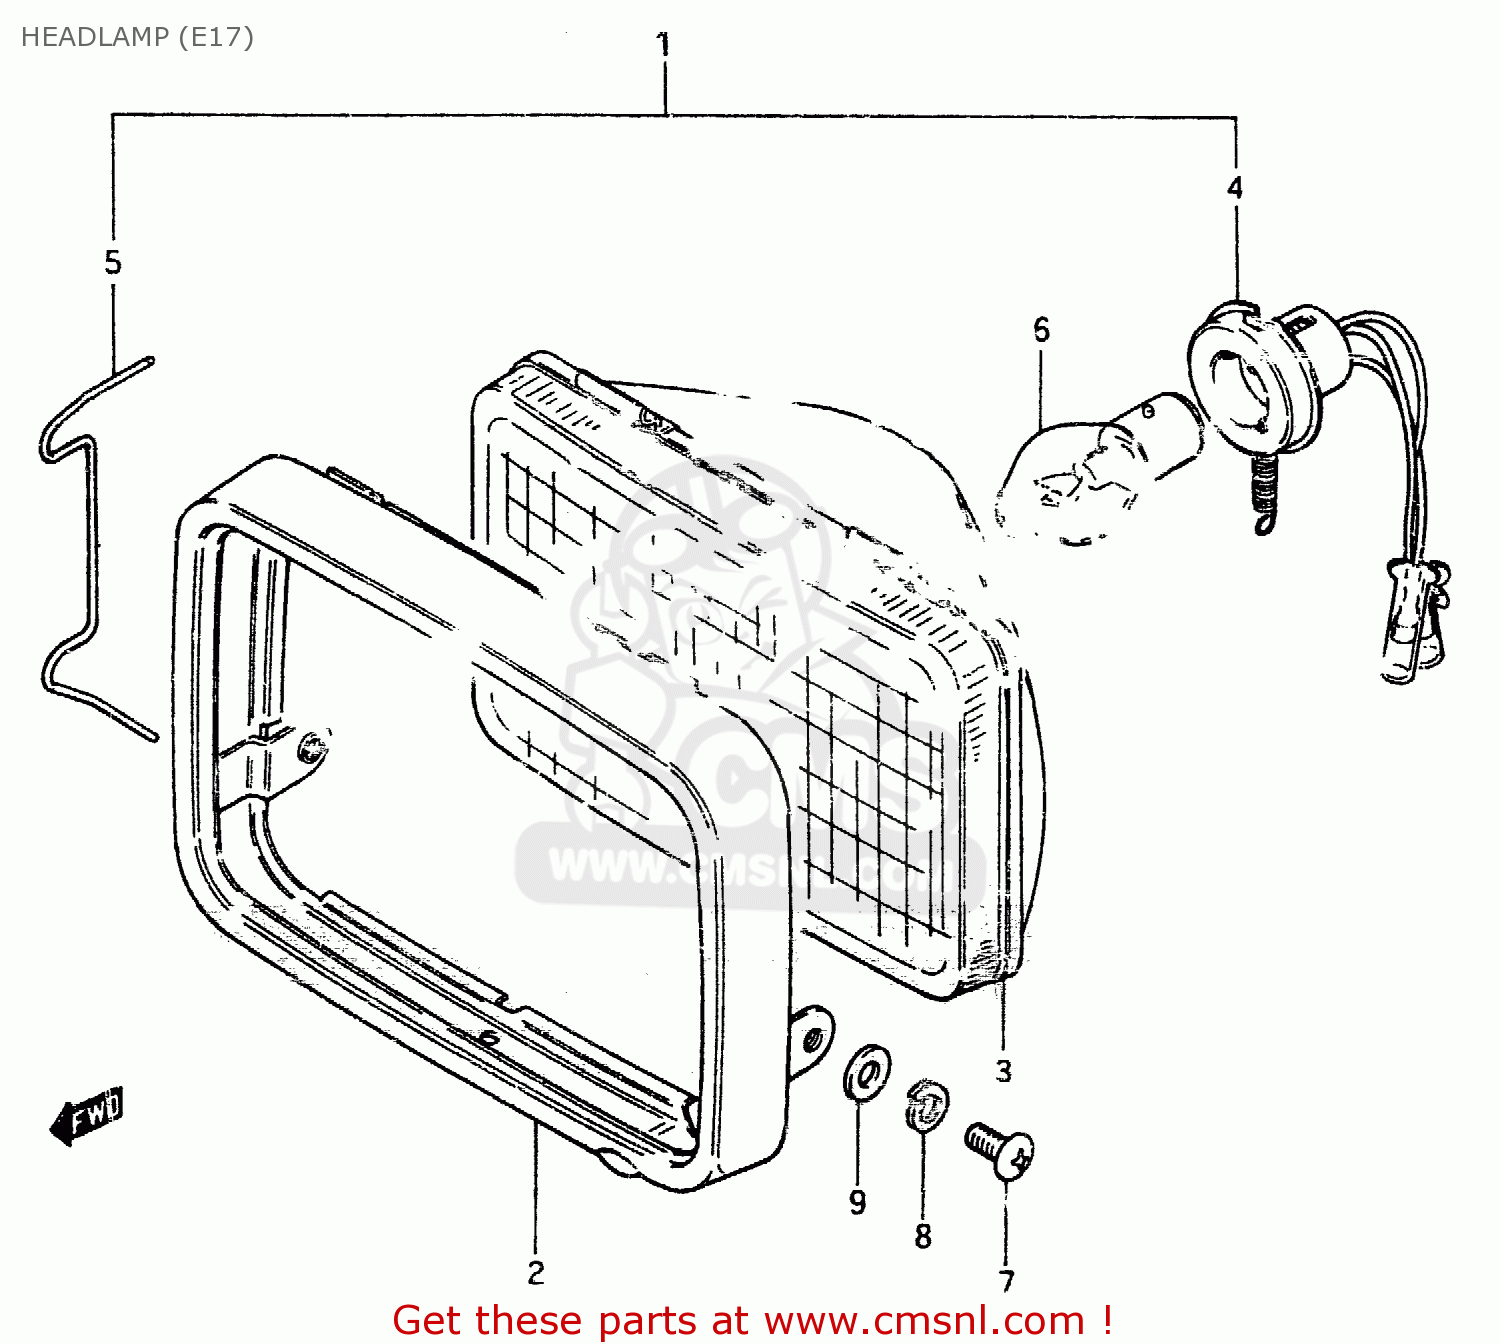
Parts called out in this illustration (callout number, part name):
1	HEADLAMP ASSY
2	RIM
3	UNIT
4	SOCKET
5	SPRING
6	BULB (6V,15/15W)
7	SCREW
8	LOCK WASHER
9	WASHER
